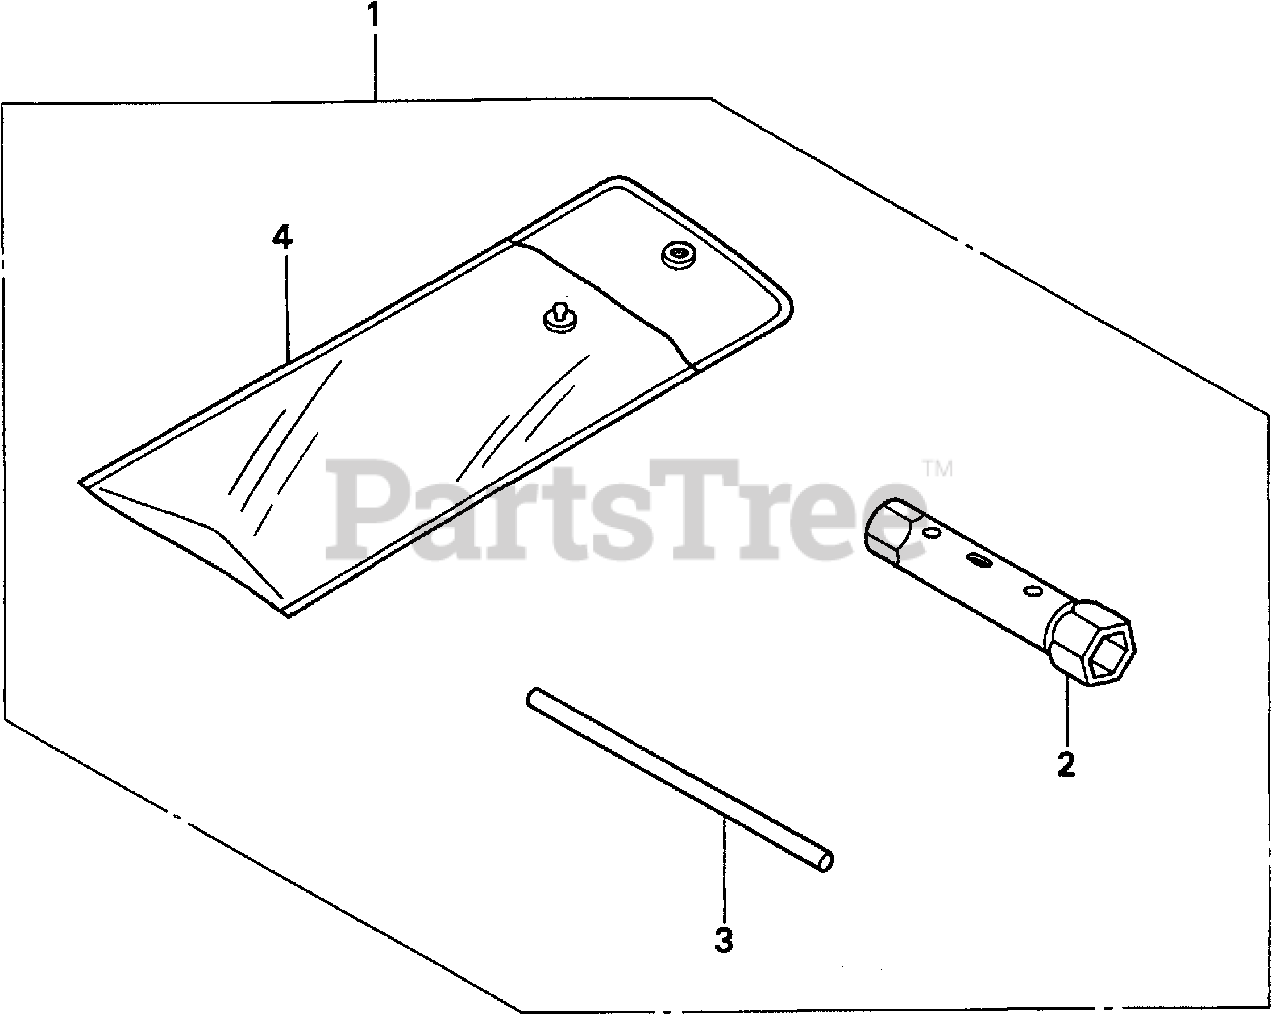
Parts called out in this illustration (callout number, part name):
1	TOOL KIT
2	WRENCH, SPARK PLUG
3	BAR A, HANDLE
4	BAG, TOOL (160MM)
